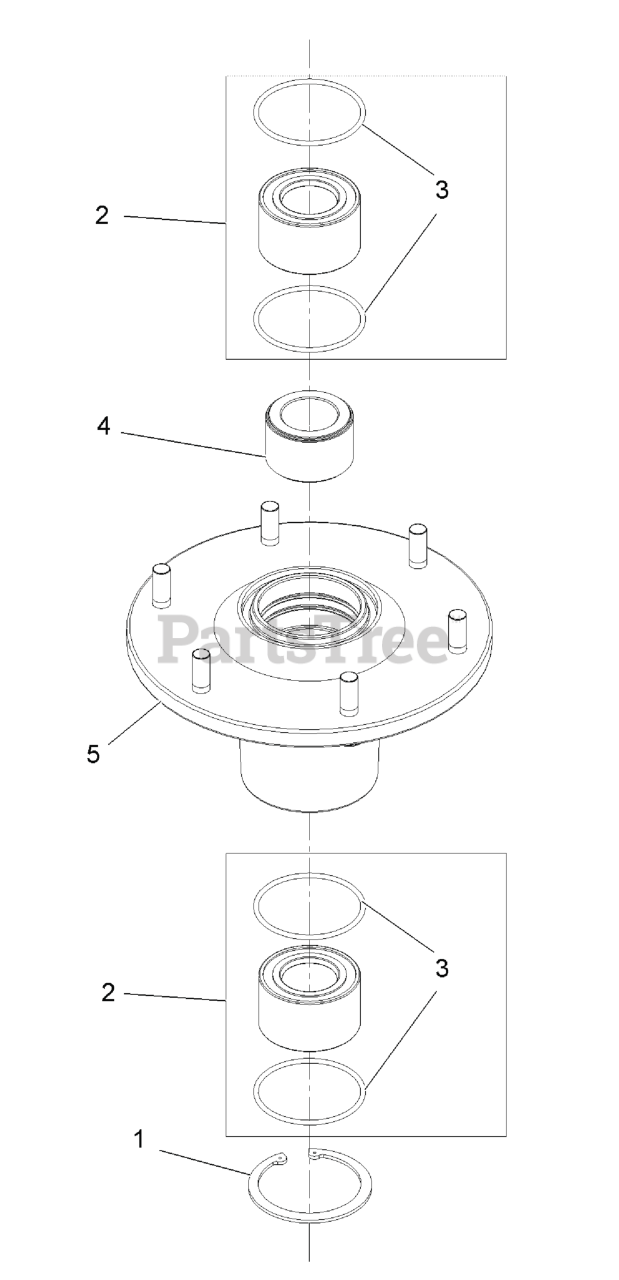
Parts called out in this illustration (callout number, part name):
1	RING-RETAINING
2	ASM, BEARING W/ORINGS
4	SPACER,BEARING
5	ASM,HOUSING W/STUDS
